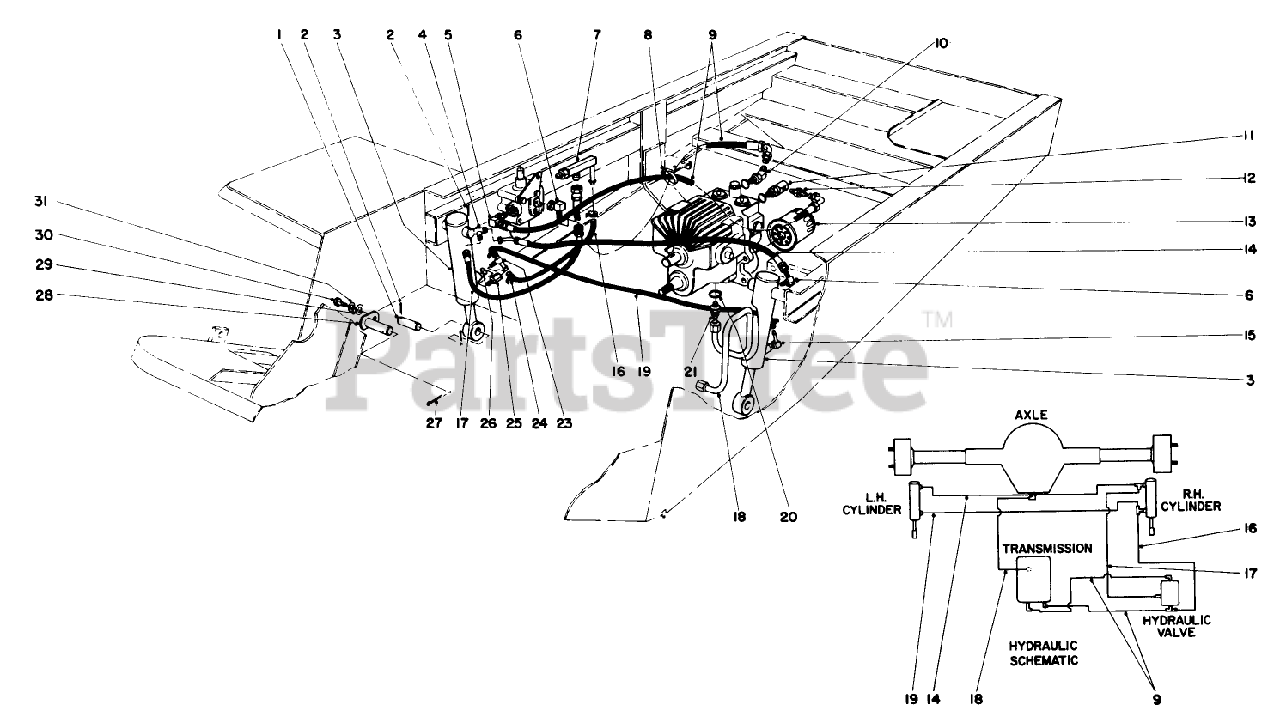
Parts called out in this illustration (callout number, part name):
1	PIN-CYLINDER
2	PIN-COTTER
3	Lift Cylinder
4	FITTING-TEE, ADJ.
5	FITTING-ELBOW, 90 DEG
6	FITTING-ELBOW, 90
7	Fitting Assembly
8	TIE-CABLE
9	TRANS-VALVE HOSE
10	FITTING-ELBOW, 45 DEG
11	SPECIAL FITTING PP
12	Adapter
13	FILTER-OIL, TRANSMISSION
14	RH CYL HOSE
15	STEM-HOSE
16	Hose Low Pressure
17	RH HOSE
18	HYORAULIC TUBE
19	HOSE-FUEL
20	O-RING
21	FITTING-STRAIGHT
23	MALE TEE FITTING
24	CLAMP-HOSE
25	CONN FITTING
26	O-RING
27	PIN-COTTER
28	Pin-Pivot
29	WASHER-FLAT
30	SCREW-HH
31	WASHER-LOCK
